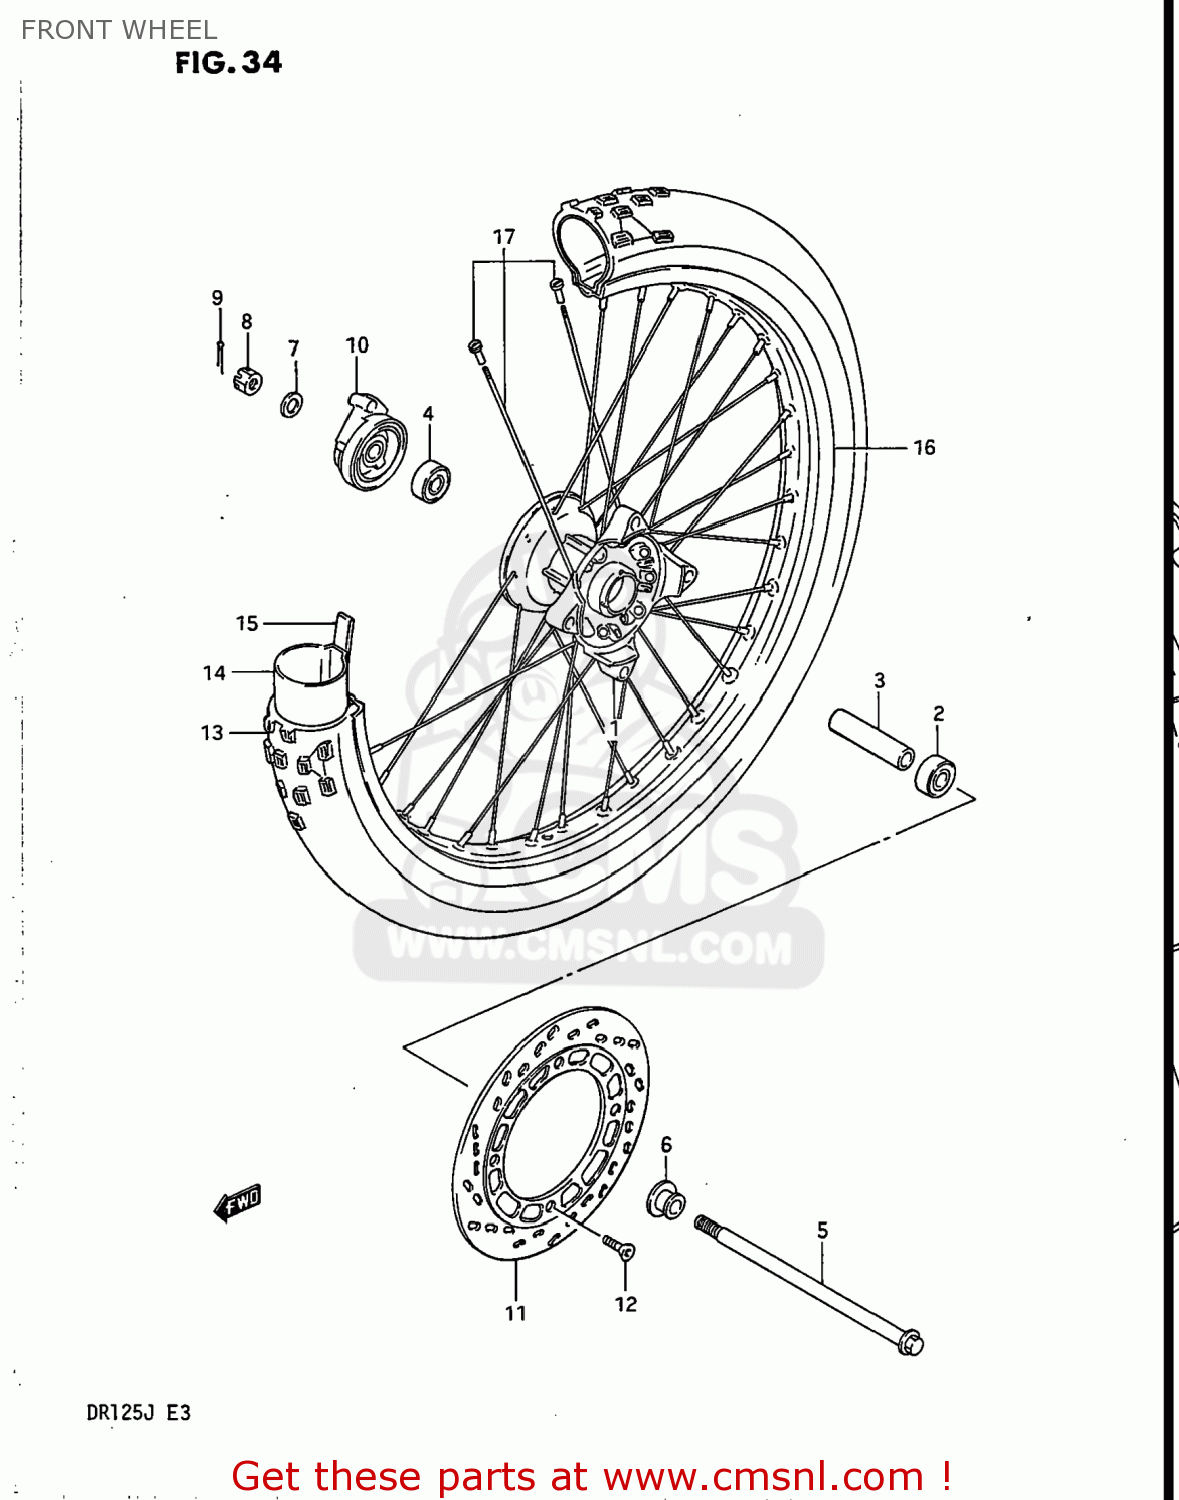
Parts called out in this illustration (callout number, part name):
1	HUB,FRONT
2	BEARING (12X32X10)
3	SPACER (12.6X19X60.5)
4	BEARING
5	AXLE,FRONT
6	SPACER,FRONT AXLE,RIGHT
7	WASHER
8	NUT 12MM
9	COTTER PIN
10	BOX ASSY,SPEEDOMETER GEAR
11	DISC,BRAKE
12	BOLT,BRAKE DISC
13	TIRE,FRONT 70/100-21
14	TUBE
15	PROTECTOR,WHEEL,INNER
16	RIM,FRONT WHEEL
17	SPOKE SET,FR WHEEL
